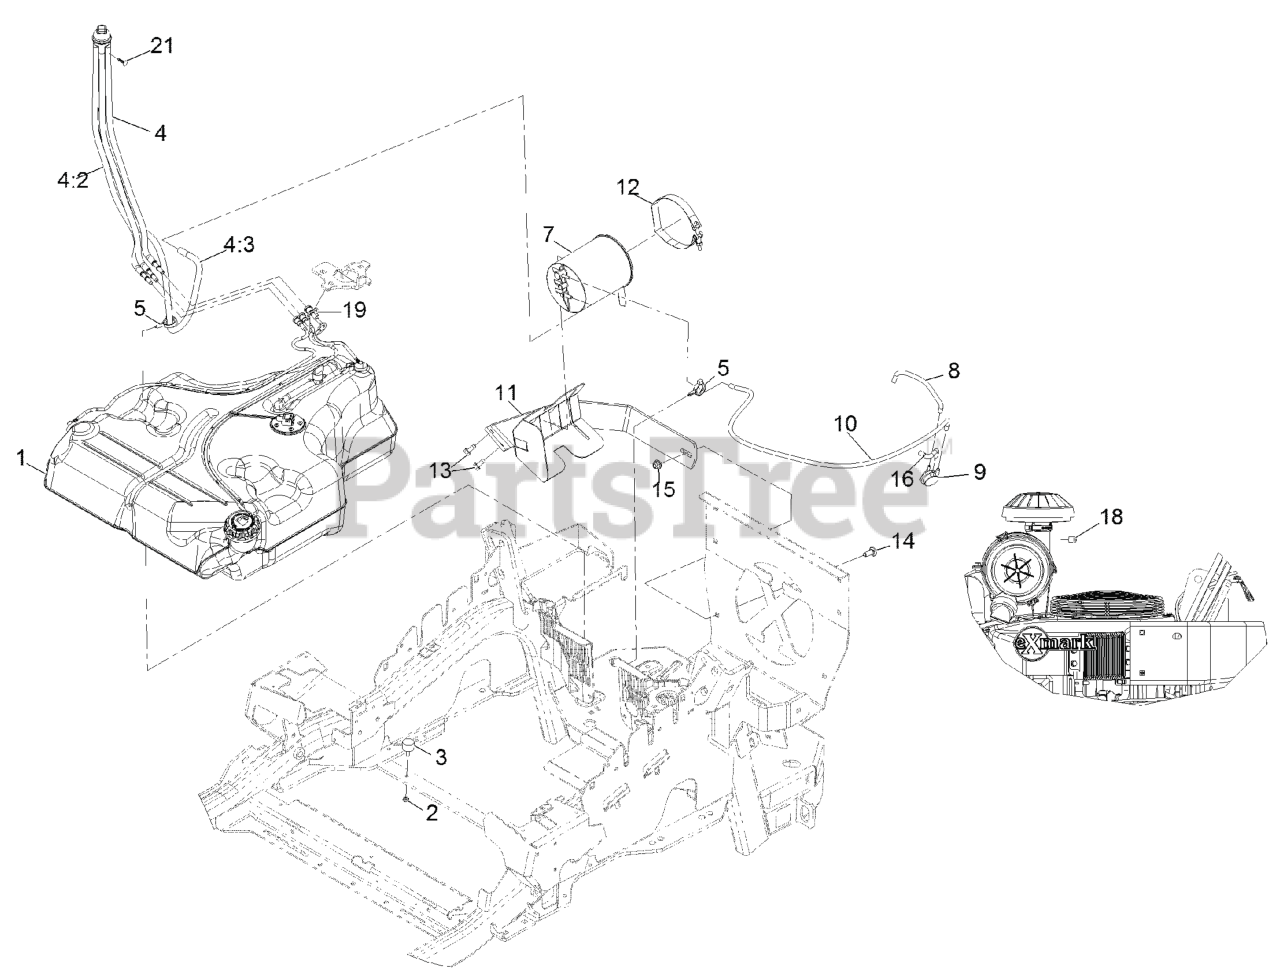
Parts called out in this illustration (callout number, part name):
1	ASM-8 GALLON FUEL TANK
2	NUT-JAM
4	FUEL MANIFOLD VENT ASM
4:2	HOSE-FUEL
4:3	HOSE-FUEL
5	CLAMP-HOSE
7	CANISTER-CARBON, 1200CC
8	HOSE-VENT,FORMED
9	VALVE-CONTROL, VACUUM
10	HOSE,VENT,FORMED
11	MOUNT-CANISTER
12	CLAMP, T-BOLT
13	Screw-HWH 5/16-18 X 3/4 Tf
14	SCREW-CARR
15	NUT-HF, NI
16	HOSE-VENT, FORMED
18	PLUG-PORT
19	RETAINER-LINE, VAPOR
21	PLUG-PLASTIC
